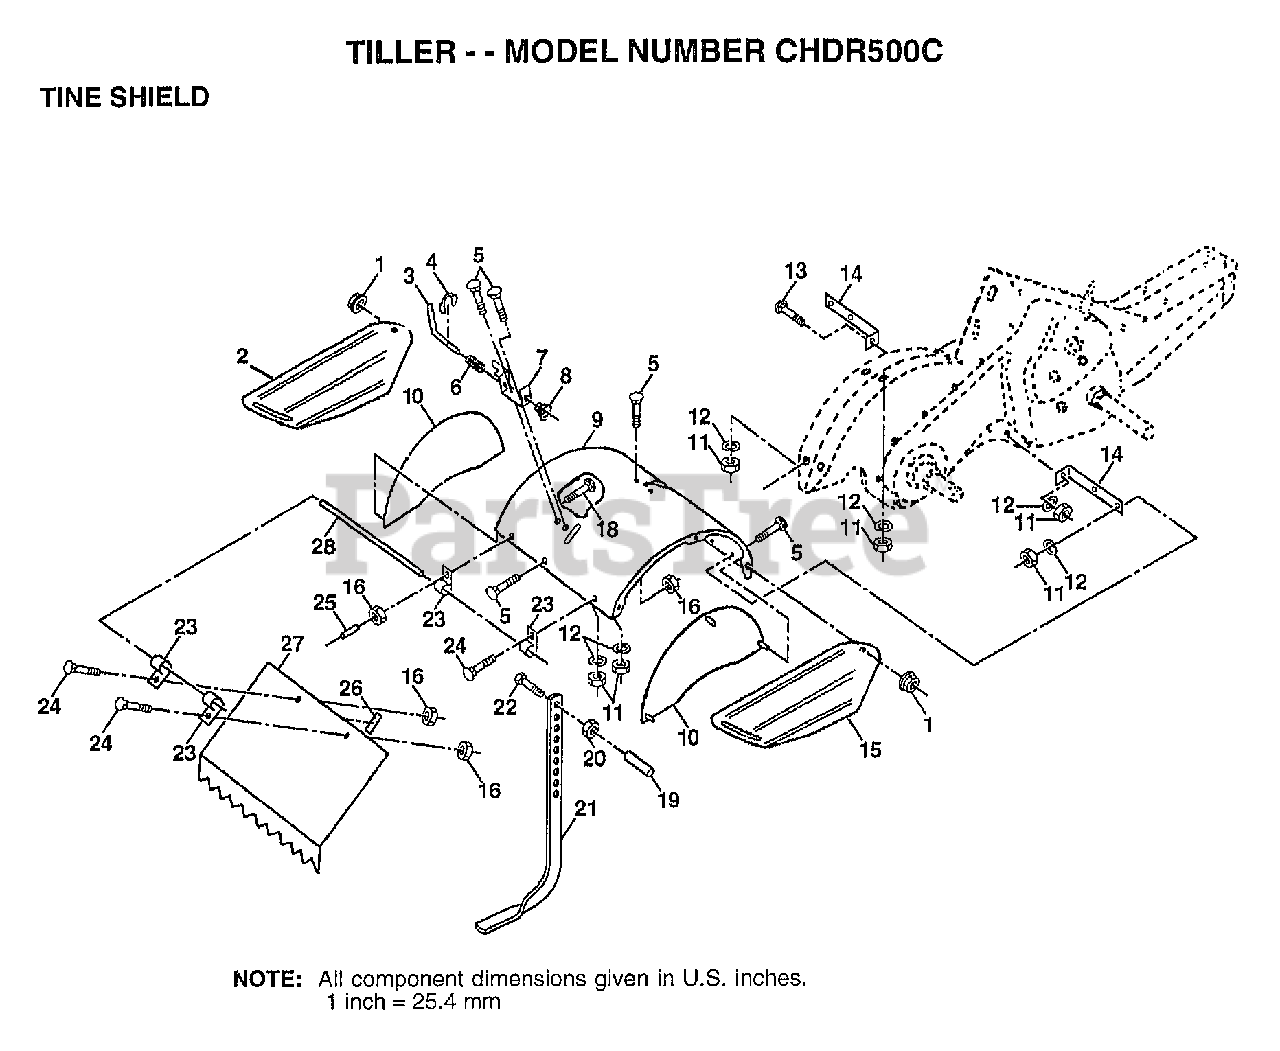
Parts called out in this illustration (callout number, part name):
1	NUT
2	SHLD.SIDE.OUTER.L
3	STAKE PIN TI
4	KLIP RING TI
5	BOLT
6	SPRING TI
7	LATCH BRACKET TI
8	SPRING CRT
9	SHIELD TINE
10	SHIELD SIDE
11	NUT.HEX.5/16-18
12	LOCKWASHER
13	BOLT
14	BRKT SHIELD TINE
15	SHLD.SIDE.OUTER.R
16	NUT
18	BOLT
19	GRIP CRT
20	NUT.HEX.3/8-16UNC
22	BOLT
23	HINGE CRT
24	BOLT
25	VINYL CAP TI
26	PAD IDLER TI
27	"SHIELD,LEVEL"
28	PIN HINGE
